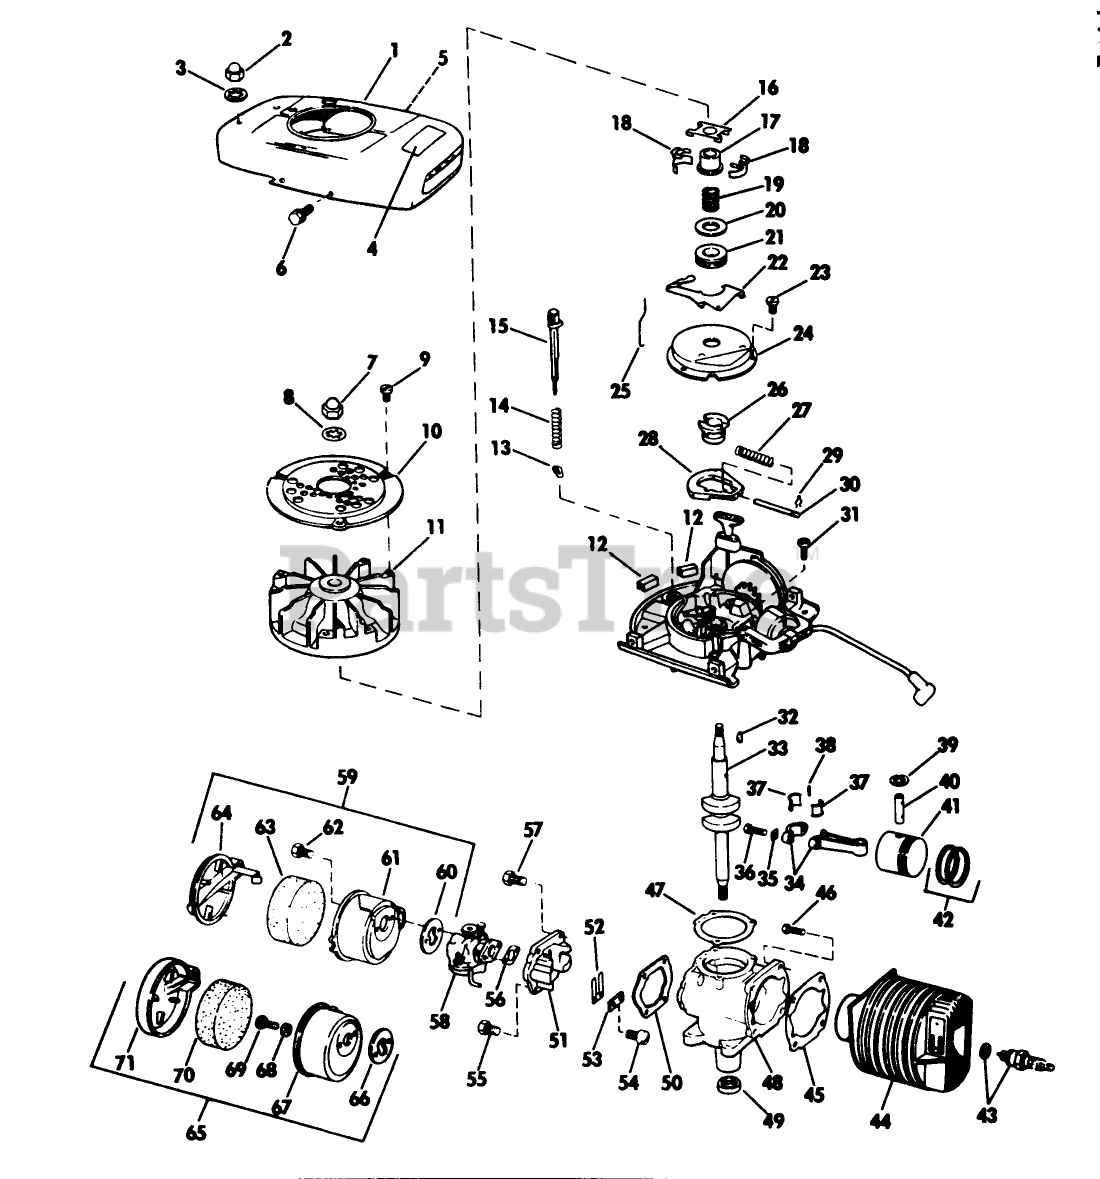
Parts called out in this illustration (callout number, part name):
2	PALNUT S
14	SPRING S
17	COLLAR S
21	THRUST COLLAR S
22	LEVER-GOVERNOR S
23	SCREW S
24	DUST COVER S
26	SPARK ADV. S
27	SPARK ADV. SPRING S
28	FLYWEIGHT S
29	SPARK ADJ. SPRING
30	PIN,SPARK ADV. S
37	LINER ASM
39	RING-RETAINING
45	GASKET S
47	GASKET S
53	PLATE-BACKUP, REED
55	SCREW S
56	GASKET S
57	SCREW S
60	GASKET S
62	SCREW S
63	AIR FIL.ELEM S
66	GASKET S
67	FILTER CHAMBER S
69	SCREW S
70	AIR FIL.ELEM S
71	CHAMBER AY S
